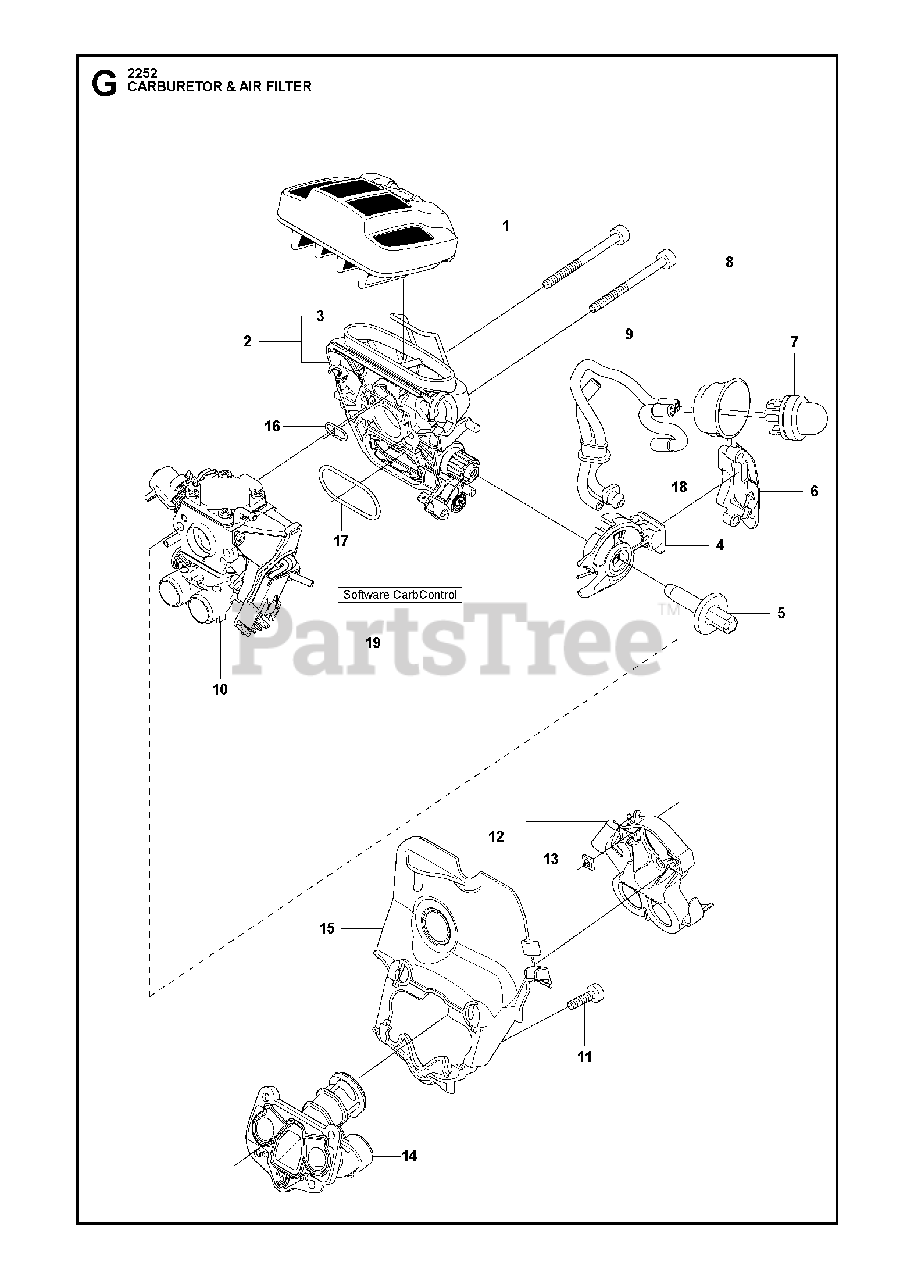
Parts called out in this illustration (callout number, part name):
1	AIR FILTER ASSY
2	FILTER HOLDER ASSY
3	SHACKLE
4	CHOKE CONTROL ASSY
7	AIR PURGE BUBBLE
10	CARBURETTOR
11	SCREW IHSCM
12	FLANGE
13	NUT
15	INTERMEDIATE WALL
18	FUEL HOSE
